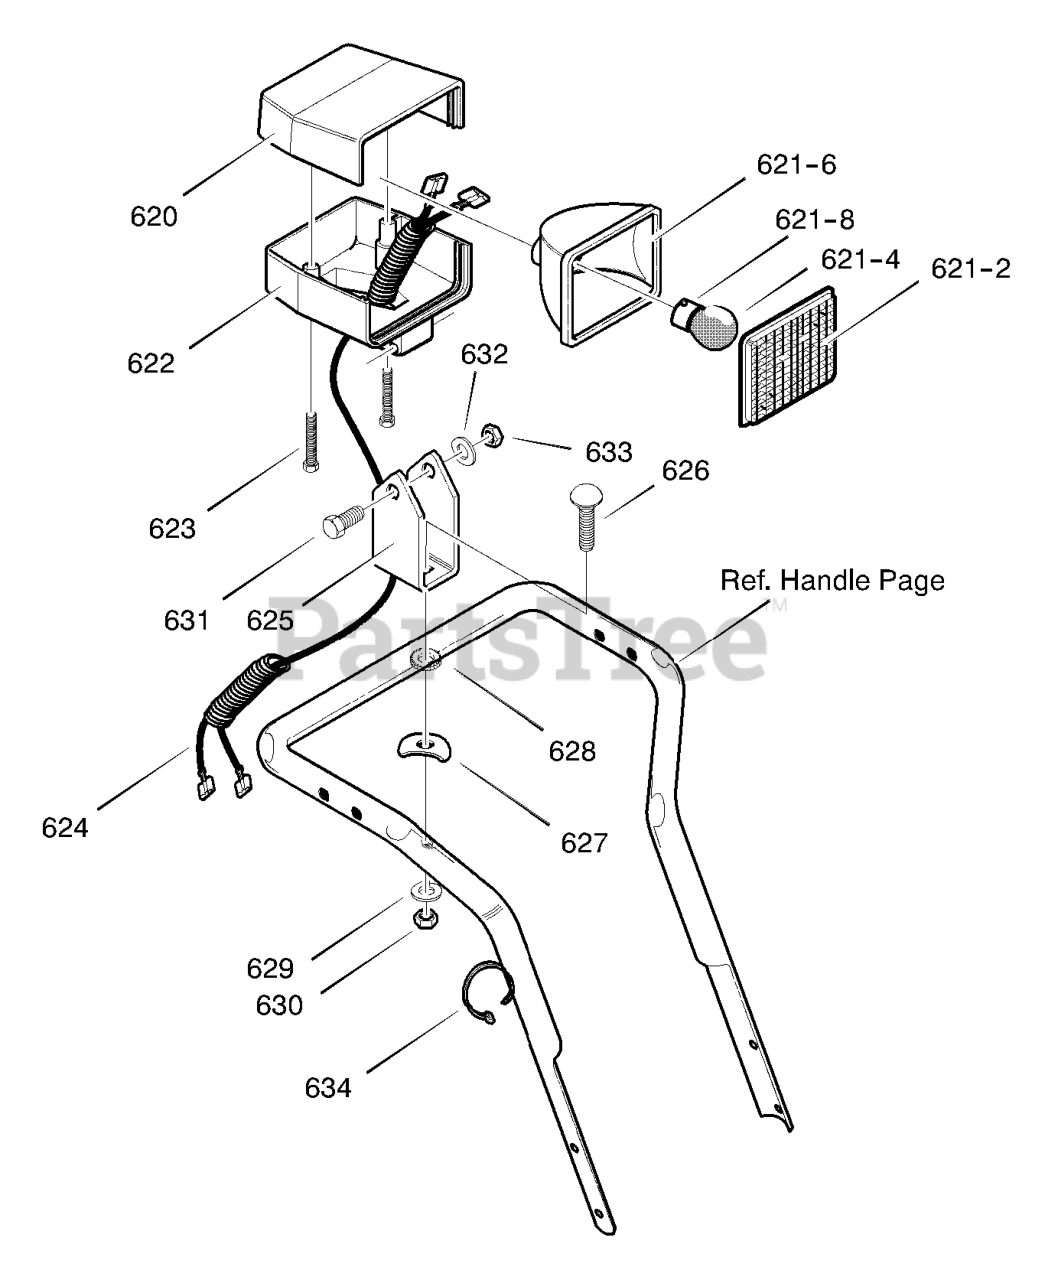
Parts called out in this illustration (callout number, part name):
620	HOUSING, HEADLIGHT UPPER
621	HEADLIGHT, ASSY
621-4	BULB 1156
621-6	BACK, METALIZED
621-8	SOCKET
622	HOUSING, HEADLIGHT LOWER
623	SCREW, #8X1.75
624	WIRING HARNESS
625	BRACKET, HEADLIGHT
626	BOLT, 5/16-18X1.75 CARR.
627	WASHER, SADDLE
628	WASHER, EXLK .32X.60X.040
629	WASHER, SPTLK .31X.58X.08
630	NUT, 5/16-18 REGHEX
631	SCREW, 5/16-18 x 2.00
632	WASHER, SPTLK
633	NUT, 5/16-18 REGHEX
634	TIE, CABLE
